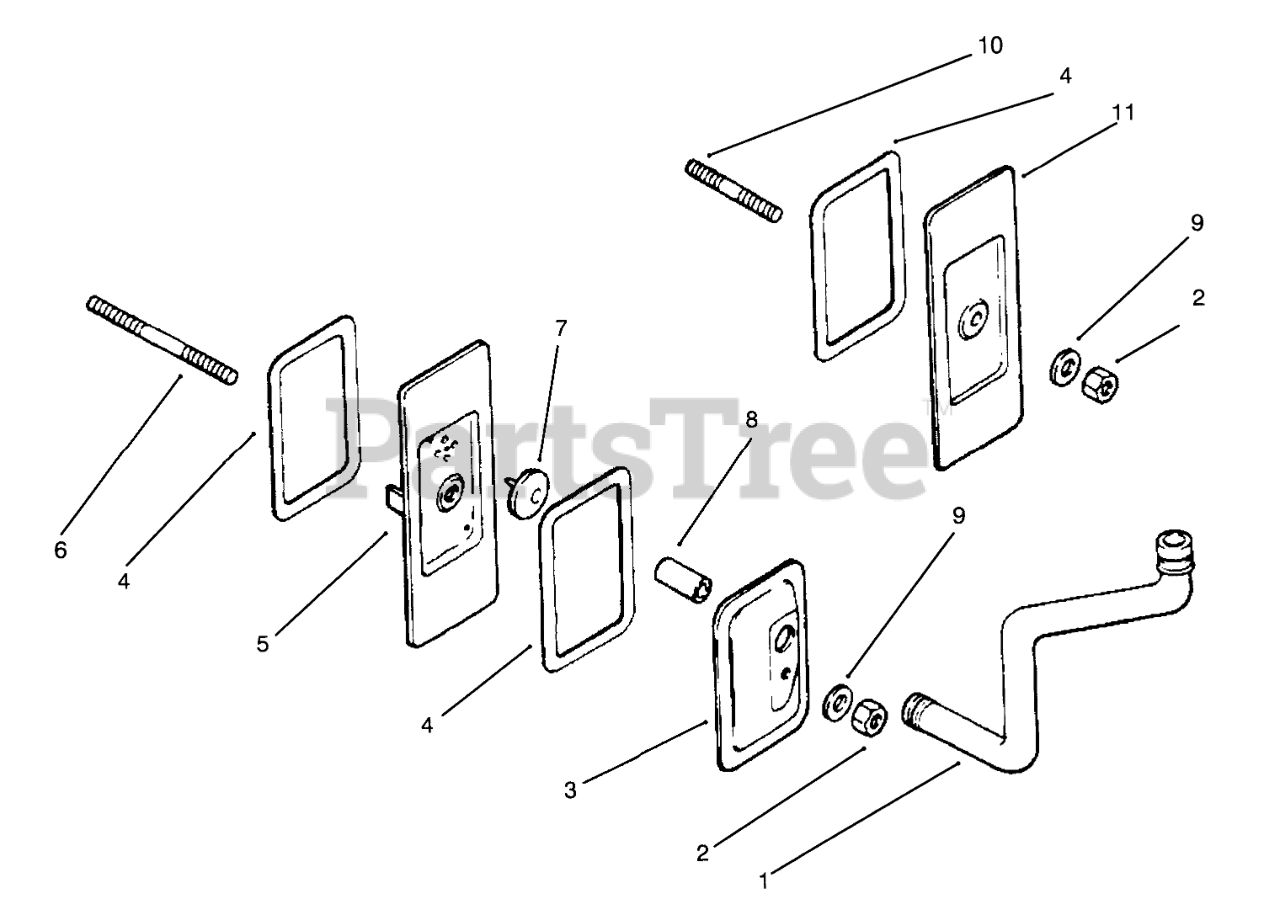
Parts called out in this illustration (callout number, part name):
1	Hose-Breather
3	Cover-#1 Upper Cyl. Valve
4	Gasket-Cover
5	Cover-#1 Lower Cyl. Valve
6	Stud
7	Valve-Umbrella
8	Seal-Breather
9	Washer
10	Stud-Valve Cover
11	Cover-Cylinder Valve
